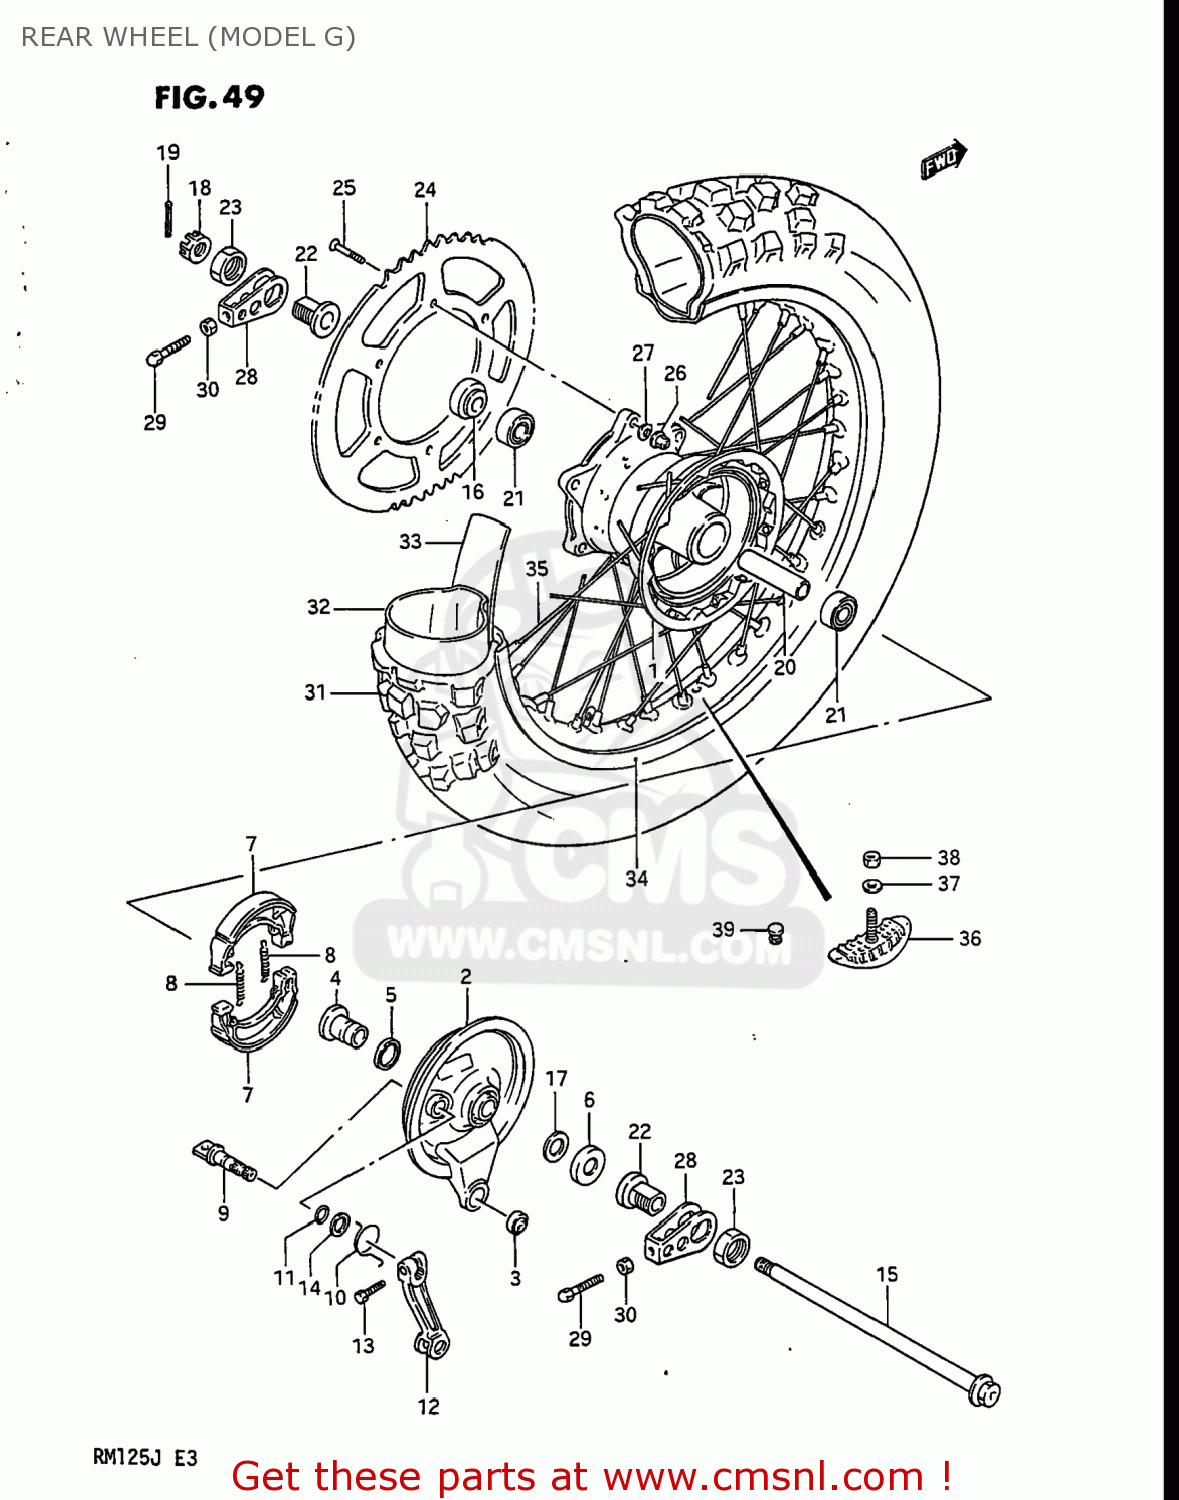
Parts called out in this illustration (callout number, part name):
1	HUB,REAR WHEEL
2	PANEL SET,REAR
3	BEARING
4	SPACER,RR BR AHR PNL
5	SEAL,OIL(20X27X5)
6	CVR,RR BRAKE AHR PNL DUST SEAL
7	SHOE,BRAKE (MCA)
8	SPRING(L:34)
9	CAM,FR BRAKE
10	SPRING
11	O RING(D:2.5,ID:11.4)
12	LEVER,REAR BRAKE CAM
13	BOLT
14	WASHER(12.5X20X1)
15	AXLE,REAR
16	SPACER,RR AXLE,L
17	WASHER,THRUST
18	NUT
19	COTTER PIN
20	SPACER,REAR HUB BEARING
21	BEARING(15X35X11)
22	SPACER,CHAIN ADJUSTER
23	NUT
24	SPROCKET,REAR
25	SCREW(8X33.5)
26	NUT
27	WASHER
28	ADJUSTER,CHAIN
29	BOLT(8X43)
30	NUT
31	TIRE
32	TUBE ASSEMBLY,WHEEL,INNER
33	PROTECTOR
34	RIM,REAR WHEEL
35	SPOKE SET,RR WHEEL
36	STOPPER,BEAD
37	WASHER
38	NUT 8MM
39	CAP(OD:12)
